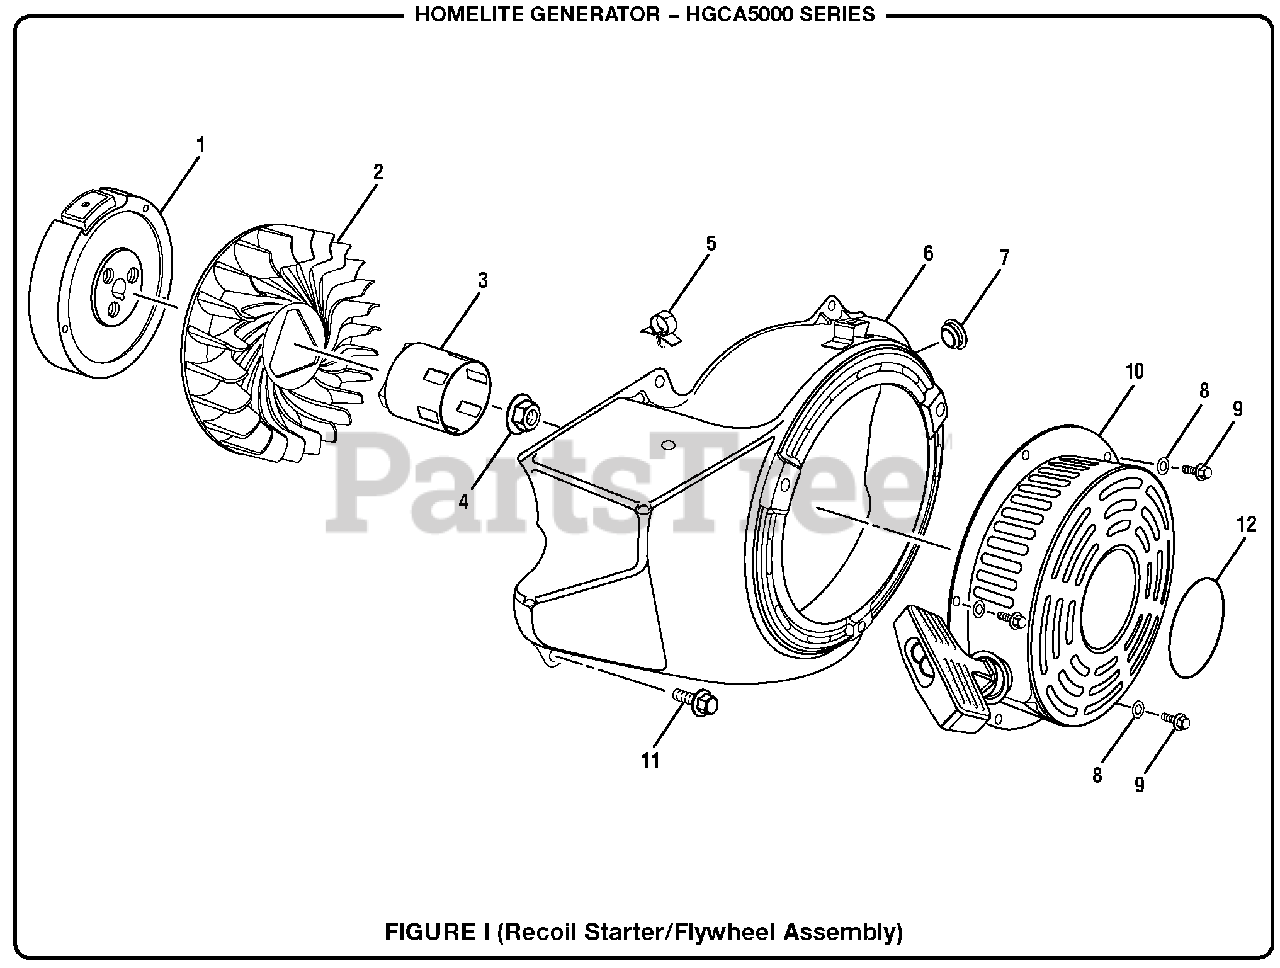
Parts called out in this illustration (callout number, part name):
2	Flywheel Fan
3	Starter Cup
4	Nut (M14 x 1.5 mm)
5	O-Ring (Fan Case)
6	Fan Case Assembly
7	Grommet (Fan Case)
8	Washer (M6)
9	Bolt (M6 x 8 mm, Flange Hd.)
10	Recoil Starter Assembly (Incl. Key Nos. 5-9)
11	Bolt (M6 x 12 mm, Flange Hd.)
12	Engine Recoil Label
